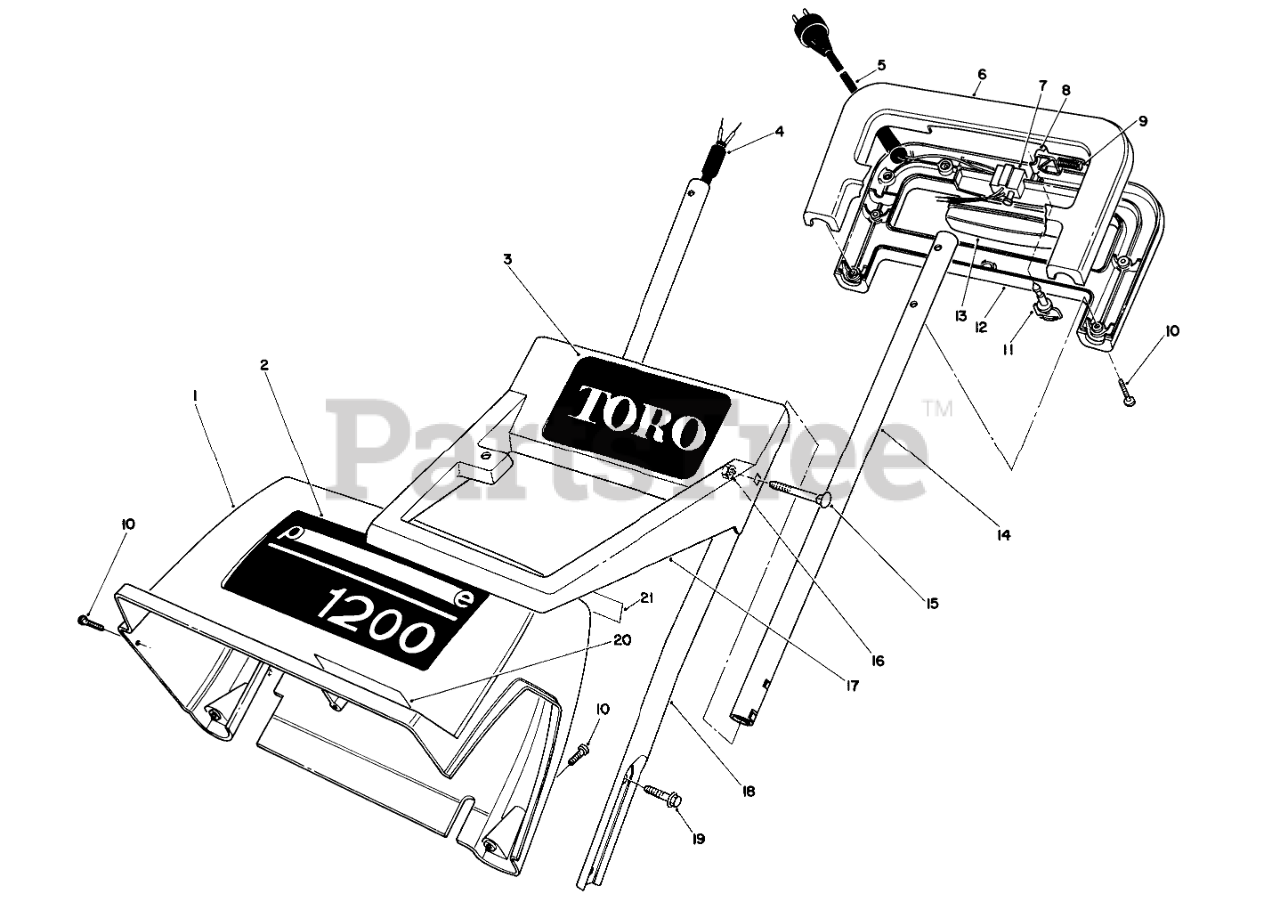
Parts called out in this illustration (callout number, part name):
1	Shroud (Incl. Ref. #2, 20, & 21)
2	DECAL-TORO 1200
3	DECAL-TORO
4	WIRE HARNESS
5	SUPPLY CORD, 1200
6	1200PC-CONTROL HANDLE U
7	SWITCH-STARTER
8	LOCKOUT, 1200
9	COMP SPRING
10	Screw
12	1200 P CONTROL HANDLE L
13	SWITCH BAR, 1200 PC
14	UPPER TUBE, S-120
16	NUT-LOCK, NI
17	MIDDLE HANDLE, 1200
18	LOWER TUBE, LH, S-120
19	SCREW-HWHTF
20	DECAL, DANGER
21	Decal-U.L.
